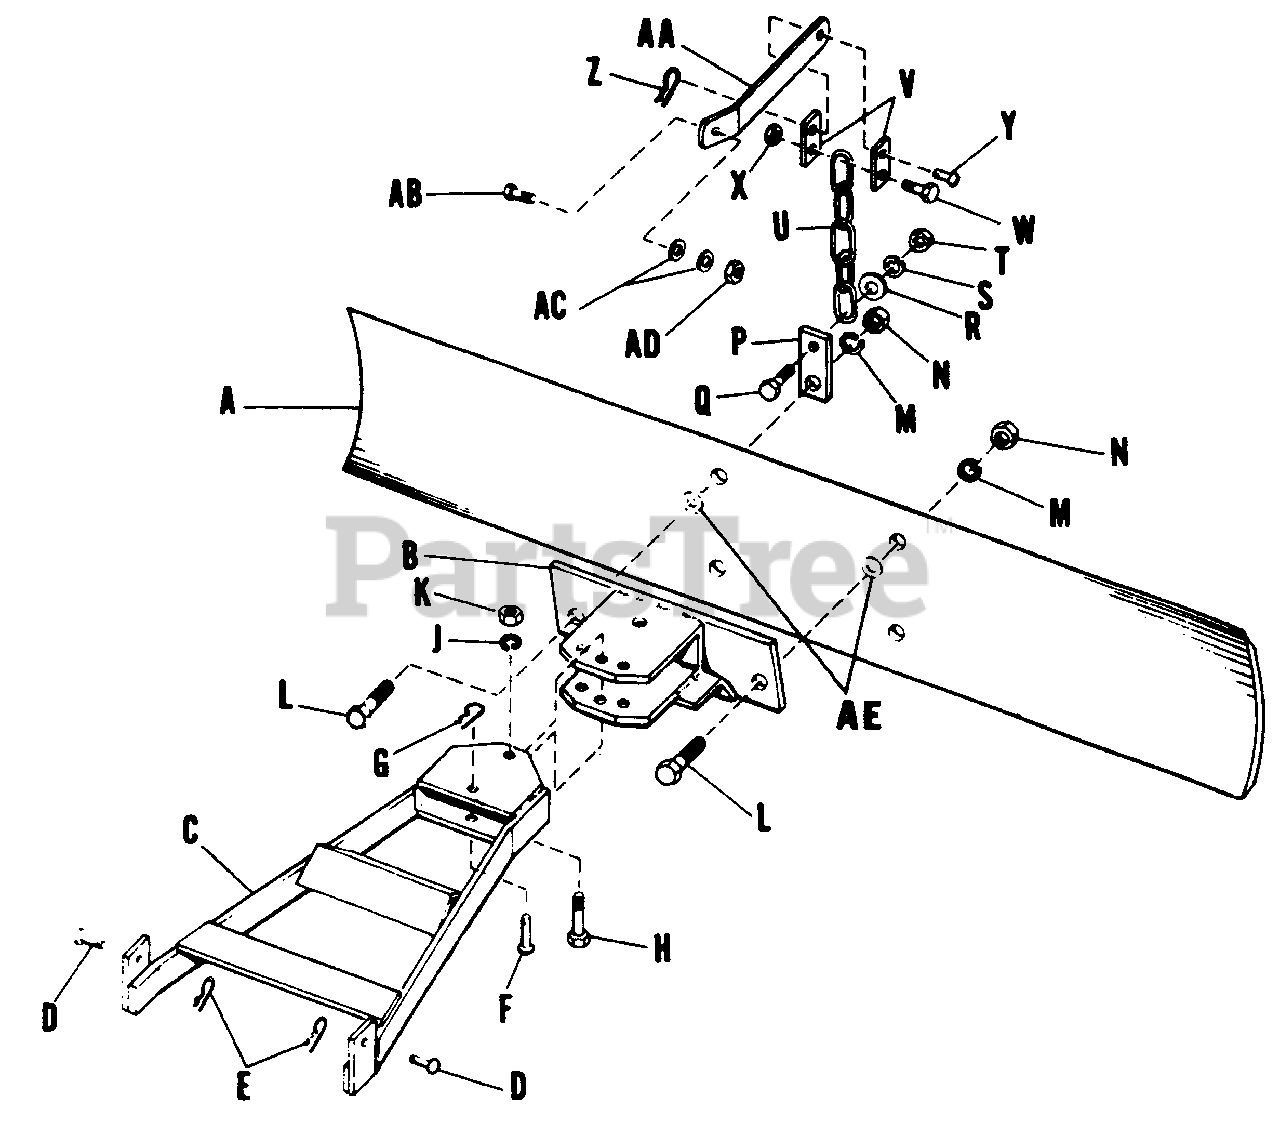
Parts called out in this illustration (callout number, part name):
A	Blade Grader, 42"
B	Hitch Assembly
C	Draw Bar Assembly
D	Pin
E	Spring Clip
G	Spring Clip
H	Capscrew, Hex Head, 5/8"-11 NC x 3" lg.
H	Capscrew. Hex Head, 5/8"-11 NC x 3" lg.
J	Lockwasher, 5/8"
K	Nut, Hex, Full. 5/8"-11 NC
L	Capscrew, Hex Head, 5/8"-11 NC x 2" lg.
M	Lockwasher, 5/8"
N	Nut. Hex, Full, 5/8"-11 NC
Q	Capscrew, Hex Head, 3/8"-16 NC x 1 1/4" lg.
R	Plain Washer, 3/8"
S	Lock Washer, 3/8"
T	Nut, Hex, Full. 3/8"-16 NC
U	Chain
W	Capscrew, Hex Head, 3/8"-16 NC x 1 1/4" lg.
X	Nut, Hex, Full, Lock, 3/8"-16 NC
Z	Spring Clip
AB	Capscrew, Hex Head, 3/8"-16 NC x 1 1/4" lg.
AC	Plain Washer, 3/8"
AD	Nut, Hex, Full, Lock, 3/8"-16 NC
AE	Flat Washer, 1-1/16"
